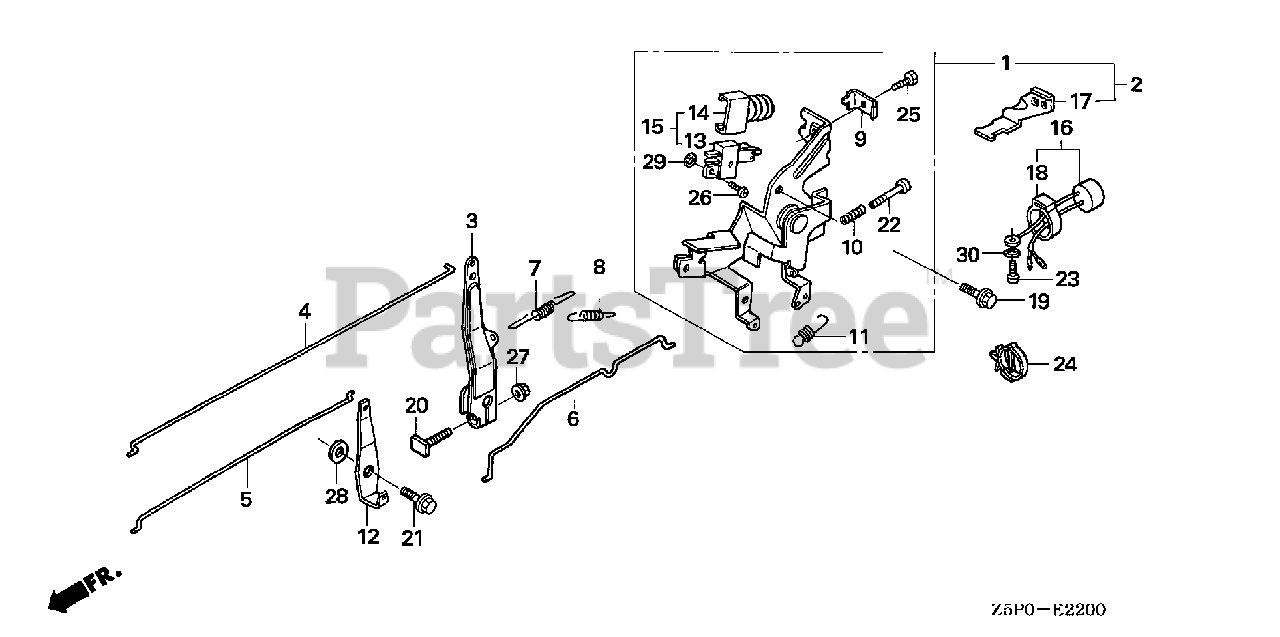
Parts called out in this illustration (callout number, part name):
1	CONTROL ASSY. (AYP)
3	ARM, GOVERNOR
4	ROD, GOVERNOR
5	ROD, CHOKE
6	ROD, JOINT
7	SPRING, GOVERNOR
8	SPRING, GOVERNOR PRIMARY
9	HOLDER, CABLE
10	SPRING, CONTROL ADJUSTING
11	SPRING, CABLE RETURN
12	LEVER, CHOKE JOINT
19	BOLT, FLANGE (6X12) (CT200)
20	BOLT, GOVERNOR ARM
21	BOLT, FLANGE (6MM)
22	SCREW, PAN (5X20)
25	BOLT, RECESSED (5X14)
27	NUT, FLANGE (6MM)
28	WASHER, PLAIN (6MM)
